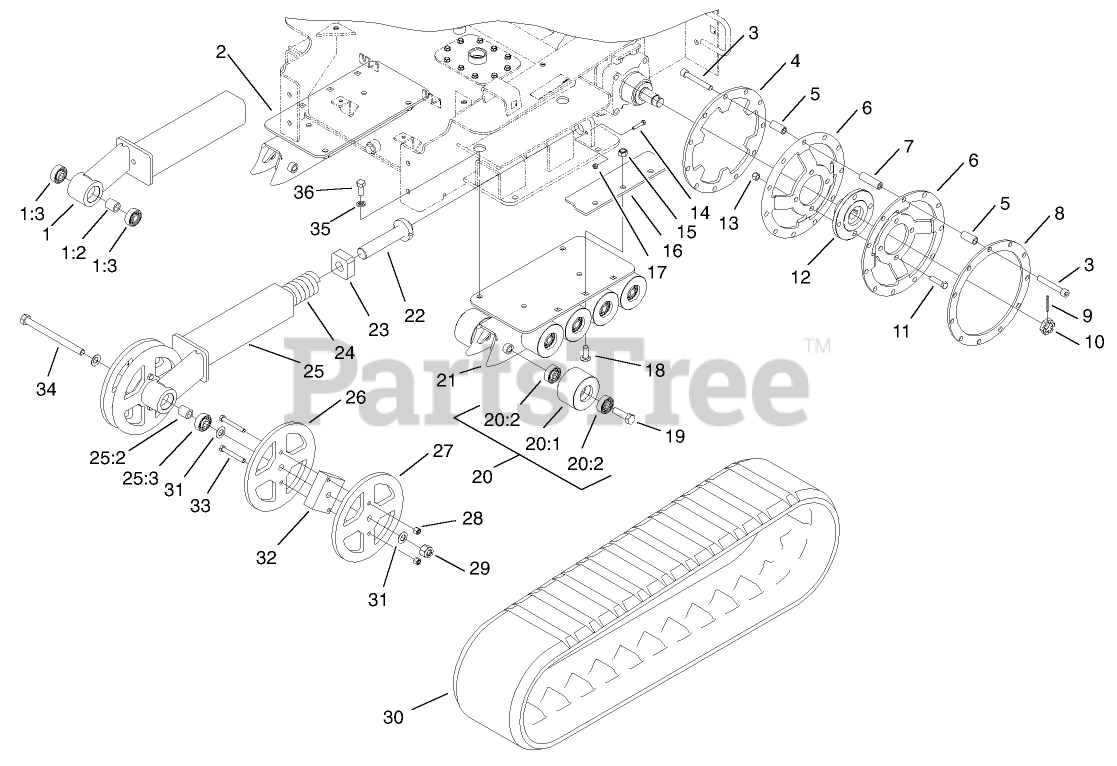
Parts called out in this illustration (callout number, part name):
1	XREF 105-5841
1:2	SPACER-BEARING
1:3	BEARING
2	RH TRACK GUIDE ASM
3	SCREW-HSH
4	RIM-BRAKE, DRIVE WHEEL
5	SPACER-WHEEL, DRIVE
6	DRIVE WHEEL ASM
7	SPACER-WHEEL, DRIVE
8	RING-WHEEL, DRIVE
9	PIN-COTTER
11	SCREW-HH
12	HUB-WHEEL, DRIVE
13	NUT-LOCK, NI
14	SCREW-HH
15	NUT-LOCK, NI
16	CLAMP-GUIDE, TRACK
17	NUT-LOCK, NI
18	SCREW-CARR, SHORT NECK
19	SCREW-HH
20	ROAD WHEEL ASM
20:1	Wheel-Road
20:2	BEARING
21	LH TRACK GUIDE ASM
22	BOLT-TENSIONER
23	BLOCK-TENSIONER
24	SPRING-COMPRESSION
25	XREF 105-5842
25:2	SPACER-BEARING
25:3	BEARING
26	WHEEL-TENSIONER, INNER
27	WHEEL-TENSIONER, OUTER
28	NUT-LOCK, NI
29	NUT-CROWNLOCK
30	TRACK
31	WASHER-BELLEVILLE
32	BLOCK-SPACER
33	SCREW-HH
34	SCREW-HEAD, SOCKET
35	WASHER-LOCK
36	SCREW-HH
